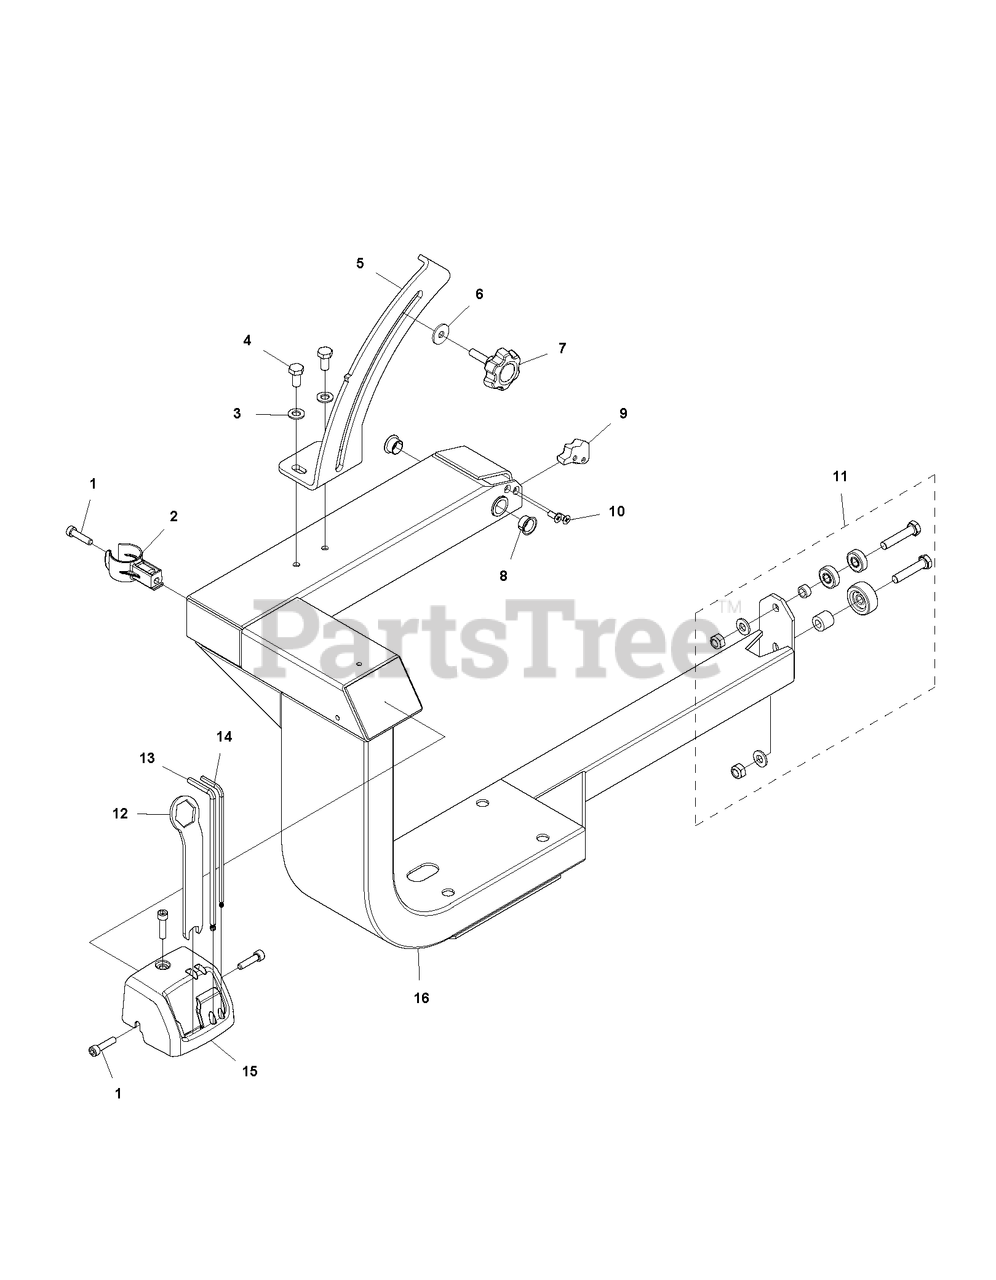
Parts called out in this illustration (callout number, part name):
1	SCREW IHSCM
3	WASHER2 pcs incl. in kit 11
4	SCREW EHHM
